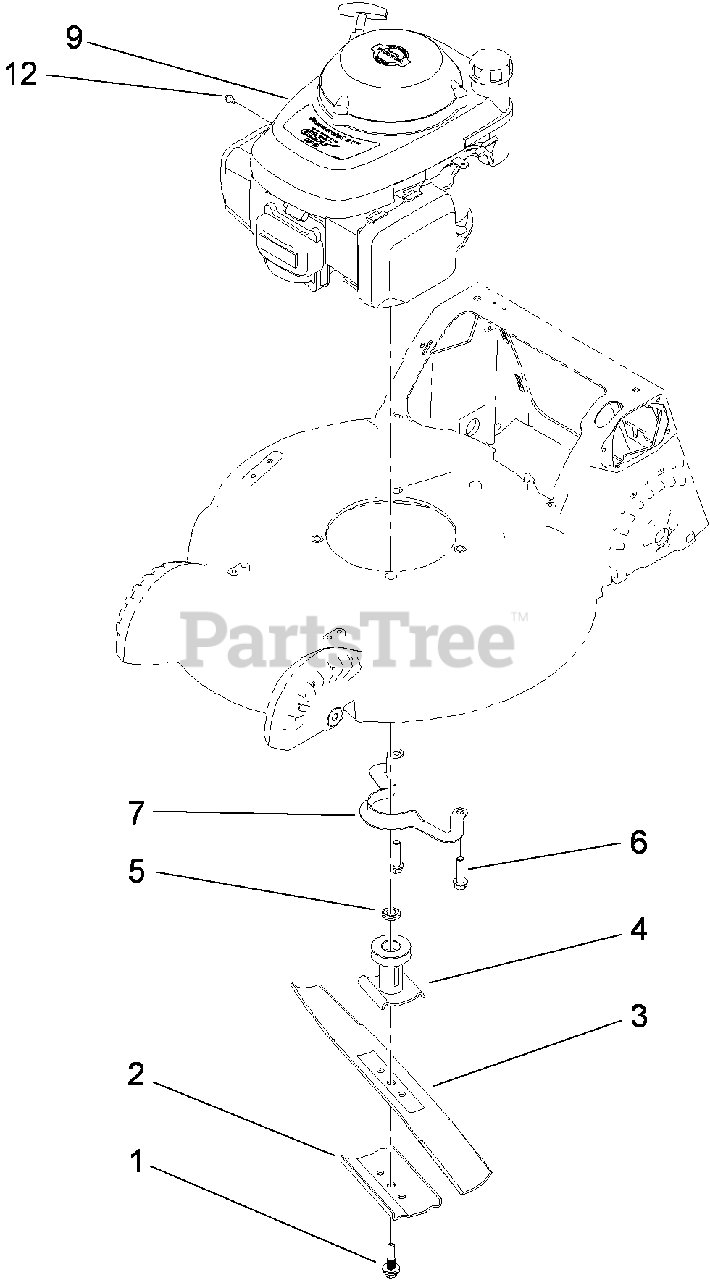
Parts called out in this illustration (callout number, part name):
1	BOLT-SHOULDER
2	SUPPORT-BLADE
3	BLADE-BAGGING
4	DRIVER-BLADE
5	Spacer-Driver
6	SCREW-HWH
12	SCREW-HWH
